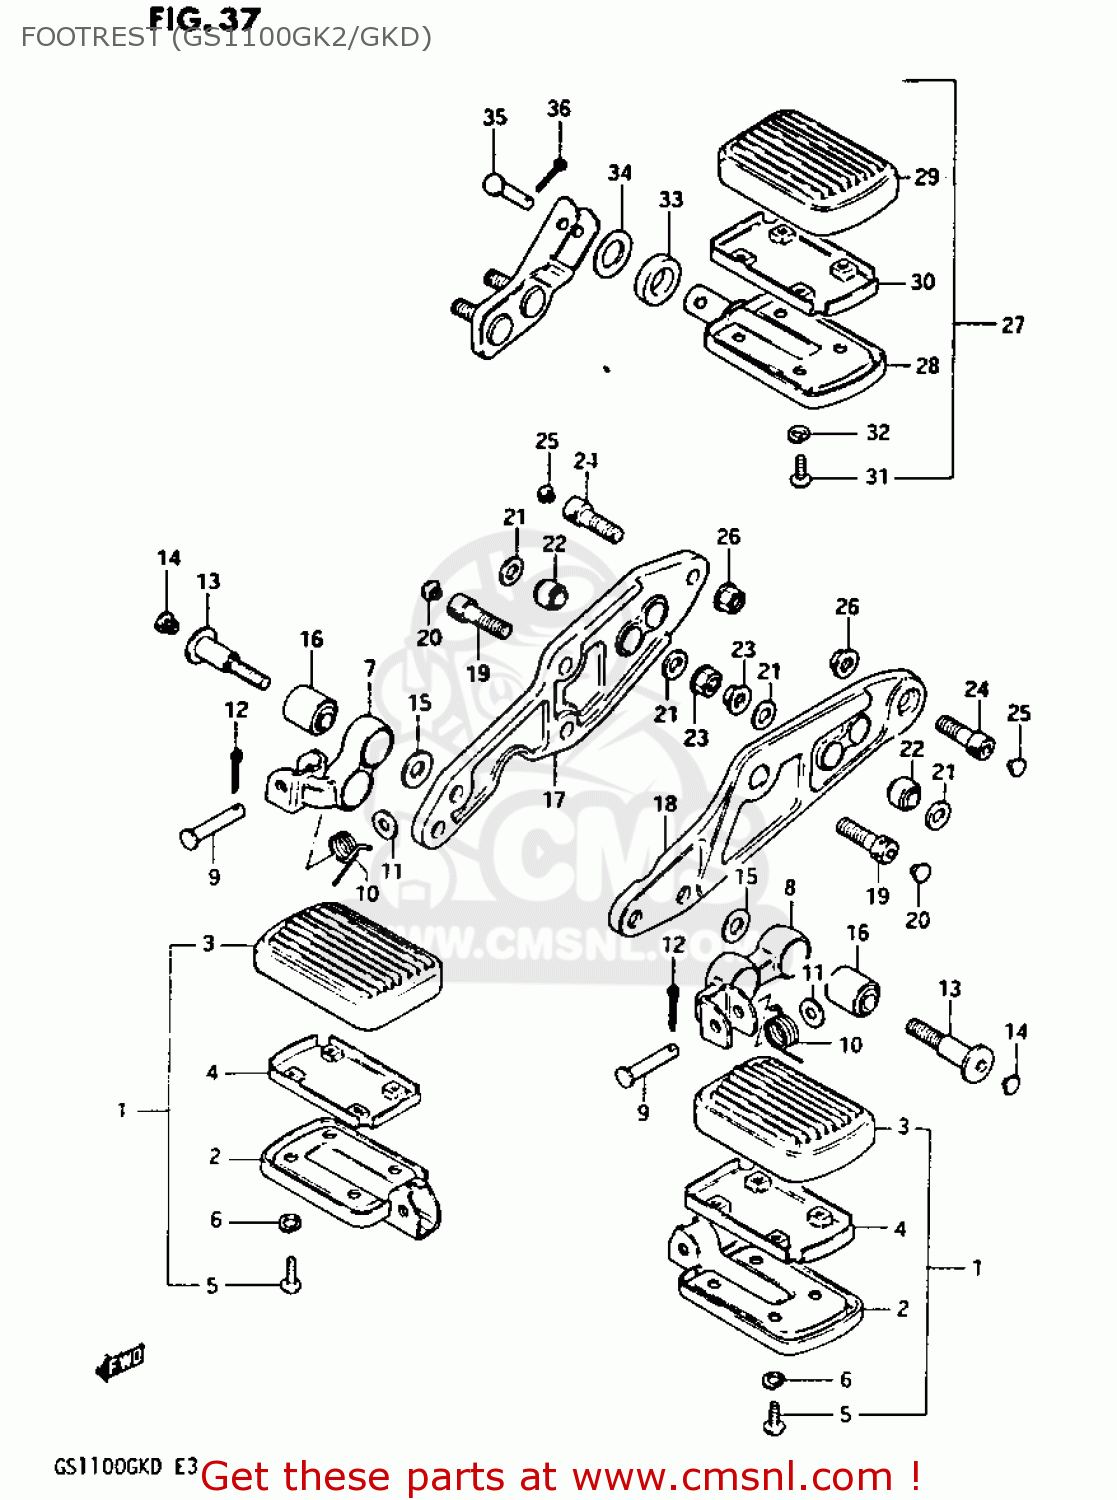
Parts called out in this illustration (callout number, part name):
1	FOOTREST ASSEMBLY,FRONT
2	HOLDER,FRONT FOOTREST
3	RUBBER,FOOTREST
4	PLATE FOOTREST
5	SCREW(5X14)
6	LOCK WASHER
7	BAR,FRONT FOOTREST,RIGHT
8	BAR,FRONT FOOTREST,LEFT
9	PIN
10	SPRING
11	WASHER
12	PIN 20X20
13	BOLT
14	CAP
15	WASHER (10.1X22X3.2)
16	BUSH(10.2X25X19)
17	BRACKET,MUFFLER,RIGHT
18	BRACKET,MUFFLER,LEFT
19	BOLT
20	CAP
21	WASHER(10.5X20X3.2)
22	BUSH
23	NUT
24	BOLT, (10X30)
25	CAP
26	NUT
27	FOOTREST ASSEMBLY,PILLION
28	BAR,REAR FOOTREST
29	RUBBER,FOOTREST
30	PLATE FOOTREST
31	SCREW(5X14)
32	LOCK WASHER
33	CUSHION
34	WASHER (19.5X32X2)
35	PIN 20X20
